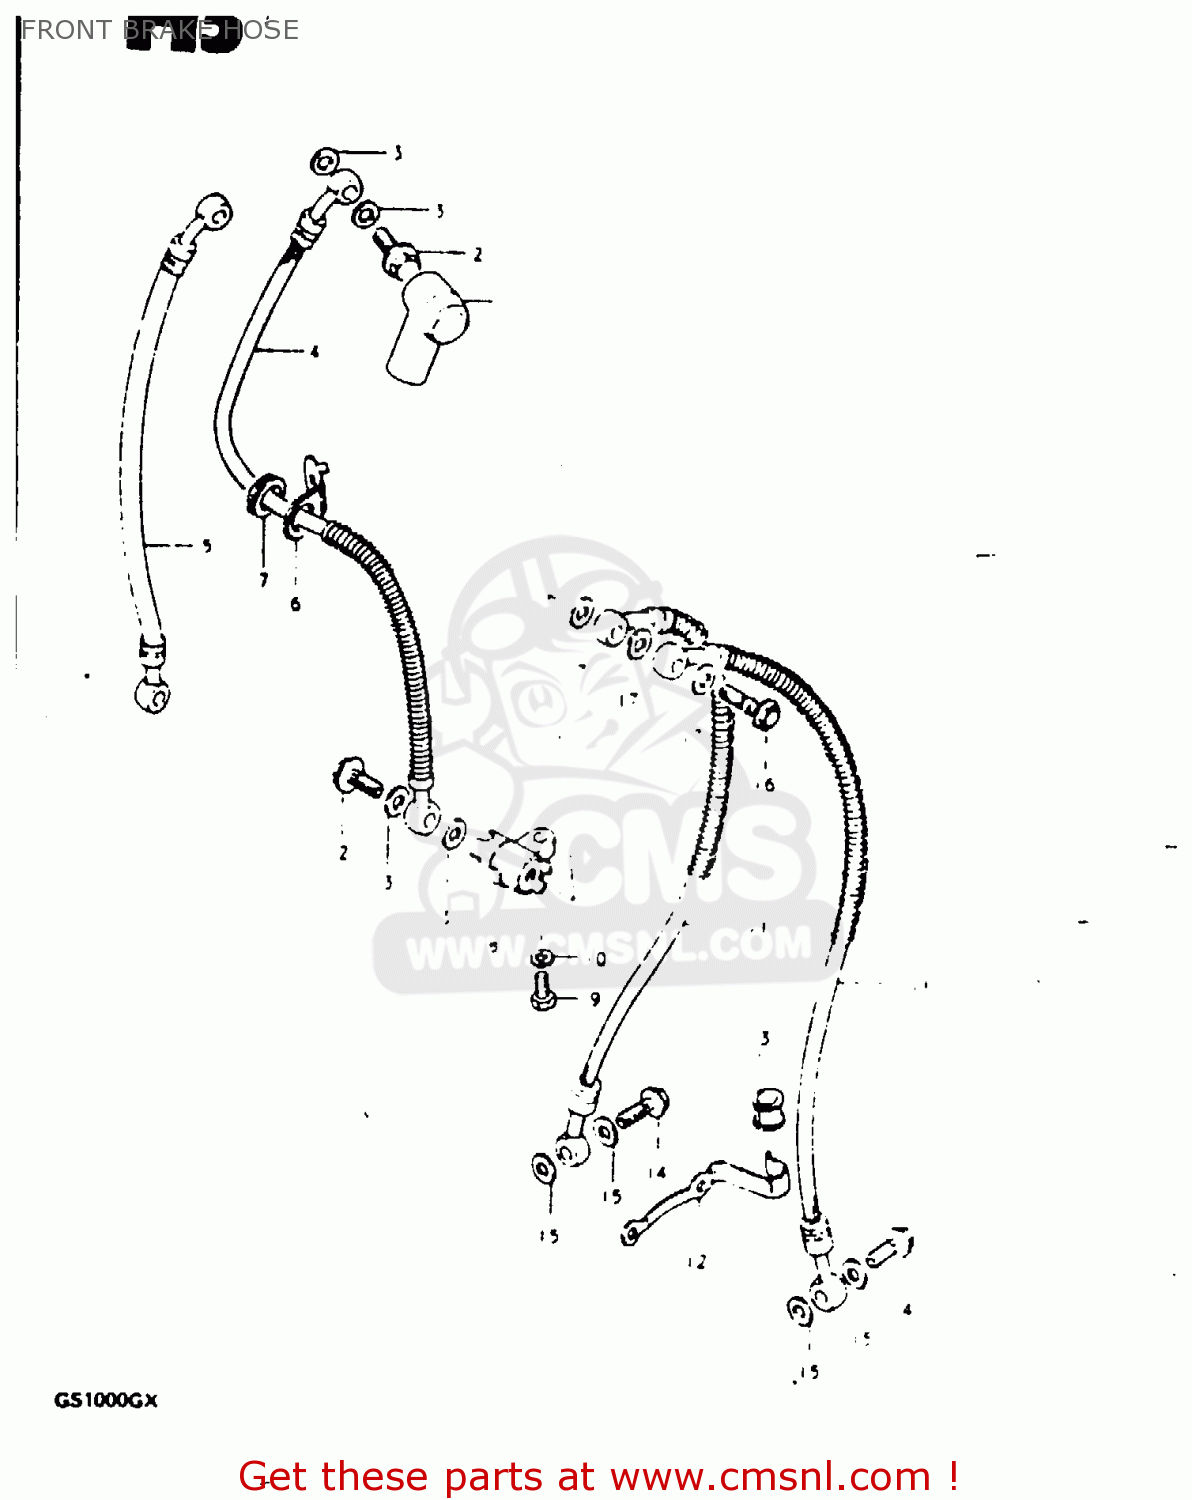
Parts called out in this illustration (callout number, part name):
1	BOOT,MASTER CYLINDER
2	BOLT,UNION
3	WASHER
4	HOSE,FRONT BRAKE
5	HOSE,FRONT BRAKE
6	GUIDE,BRAKE HOSE NO.1
7	GROMMET
8	JOINT,BRAKE HOSE
9	BOLT
10	LOCK WASHER
11	HOSE,FRONT BRAKE
12	GUIDE,BRAKE HOSE NO.2
13	BUSH,BRAKE HOSE GUIDE,NO.2
14	BOLT,UNION
15	WASHER
16	BOLT,UNION
17	WASHER
